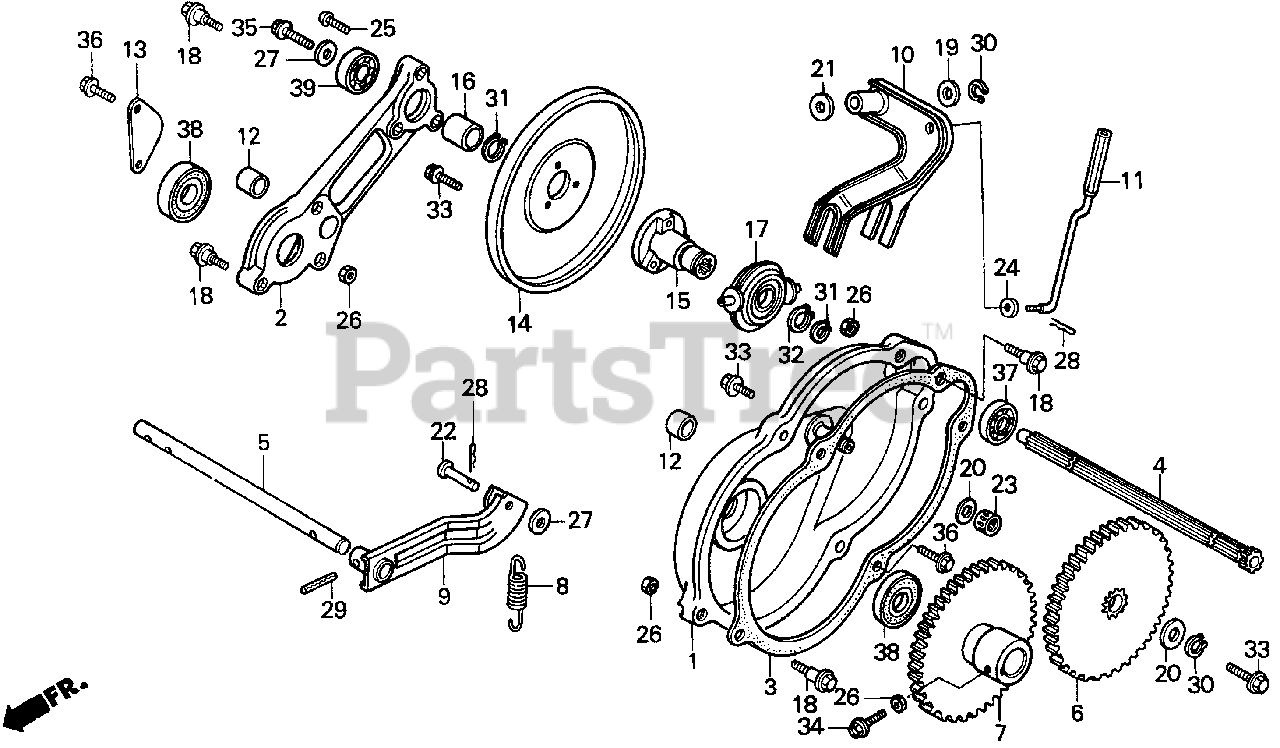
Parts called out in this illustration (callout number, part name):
1	CASE, L. TRANSMISSION (NOT AVAILABLE)
2	CASE, R. TRANSMISSION (NOT AVAILABLE)
3	GASKET, TRANSMISSION CASE
4	SHAFT, FRICTION DISK
5	SHAFT, DISK HOLDER
6	GEAR, COUNTER
7	GEAR, FINAL (NOT AVAILABLE)
8	SPRING, DRIVE DISK RETURN (NOT AVAILABLE)
9	ARM, CLUTCH
10	ARM, CHANGE
11	JOINT, CHANGE
12	BUSH, DRIVE DISK SHAFT
13	PLATE, DISK HOLDER SHAFT
14	DISK, FRICTION
15	BOSS, FRICTION DISK (NOT AVAILABLE)
16	COLLAR, FRICTION (NOT AVAILABLE)
17	ROLLER (NOT AVAILABLE)
18	BOLT, TRANSMISSION SETTING
19	WASHER, THRUST (12MM)
20	WASHER C, THRUST (12MM) (0.7)
21	WASHER, THRUST (12MM)
22	PIN, CLUTCH ARM
23	BEARING, NEEDLE (12MM)
24	COLLAR, CHANGE JOINT
25	SCREW, PAN (6X18)
26	NUT, HEX. (6MM)
27	WASHER, PLAIN (6MM)
28	PIN, LOCK (6MM)
29	PIN, SPRING (6X25)
30	CIRCLIP (OUTER) (12MM)
31	CIRCLIP (OUTER) (15MM)
32	CIRCLIP (OUTER) (22MM)
33	BOLT, FLANGE (6X12)
34	BOLT, FLANGE (6X16)
35	BOLT, FLANGE (6X16)
35	BOLT, FLANGE (6X14)
36	BOLT, FLANGE (6X18)
37	BEARING, RADIAL BALL
38	BEARING, RADIAL BALL (6004UU)
39	BEARING, RADIAL BALL (6201UU)
